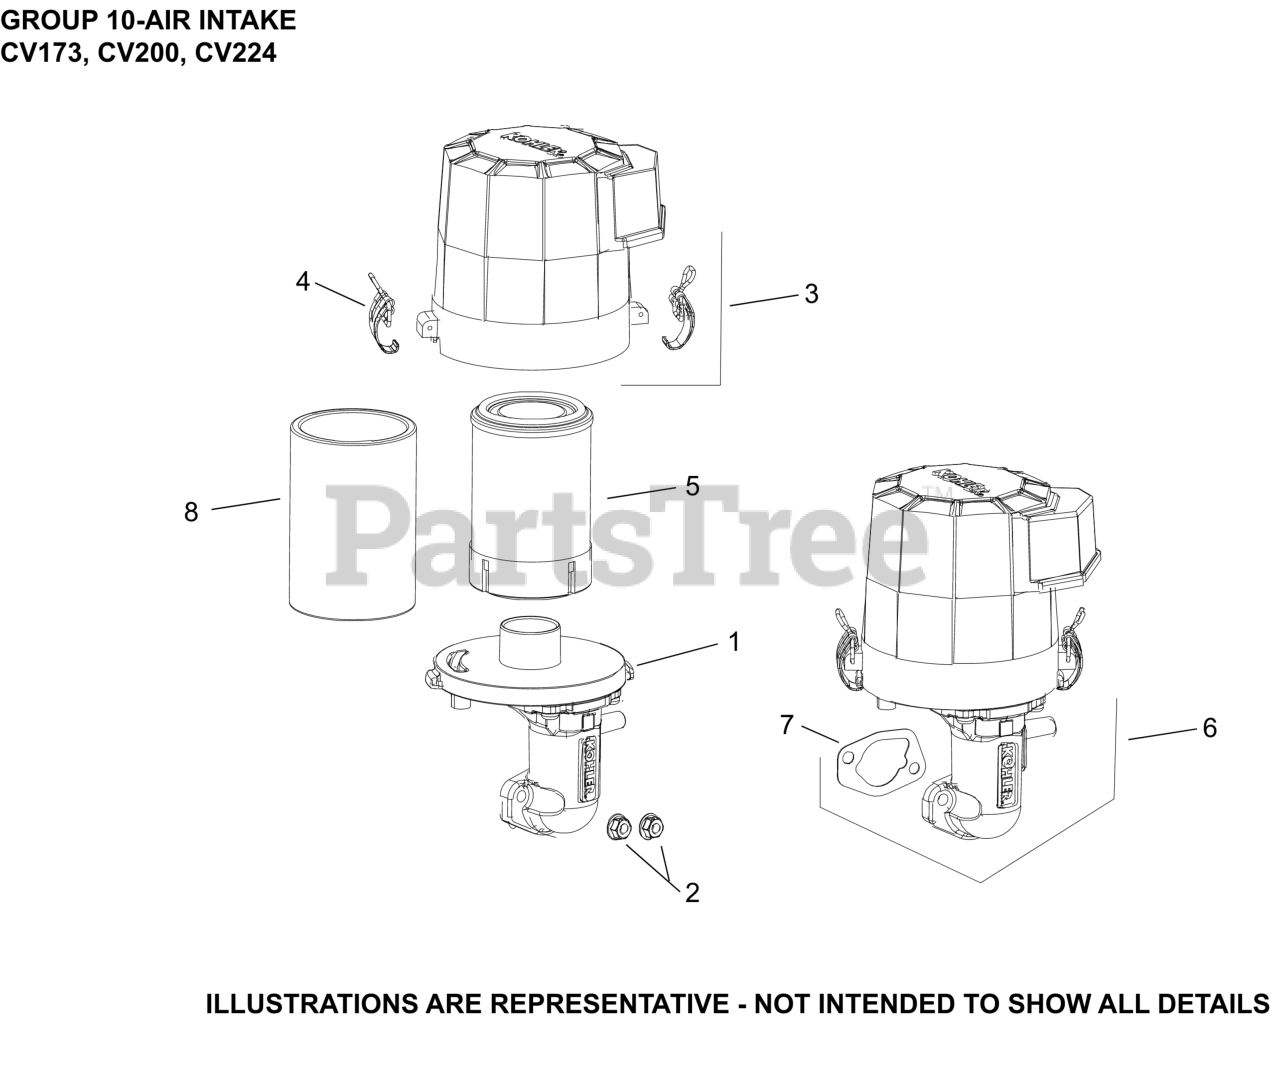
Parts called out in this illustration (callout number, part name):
1	BASE, AIR CLEANER CYCLONIC ASSEMBLY
2	NUT, HEX FLANGE LOCK (M6)
3	COVER, AIR CLEANER ASSEMBLY
4	KIT, LATCH CLIP
5	ELEMENT, AIR FILTER
